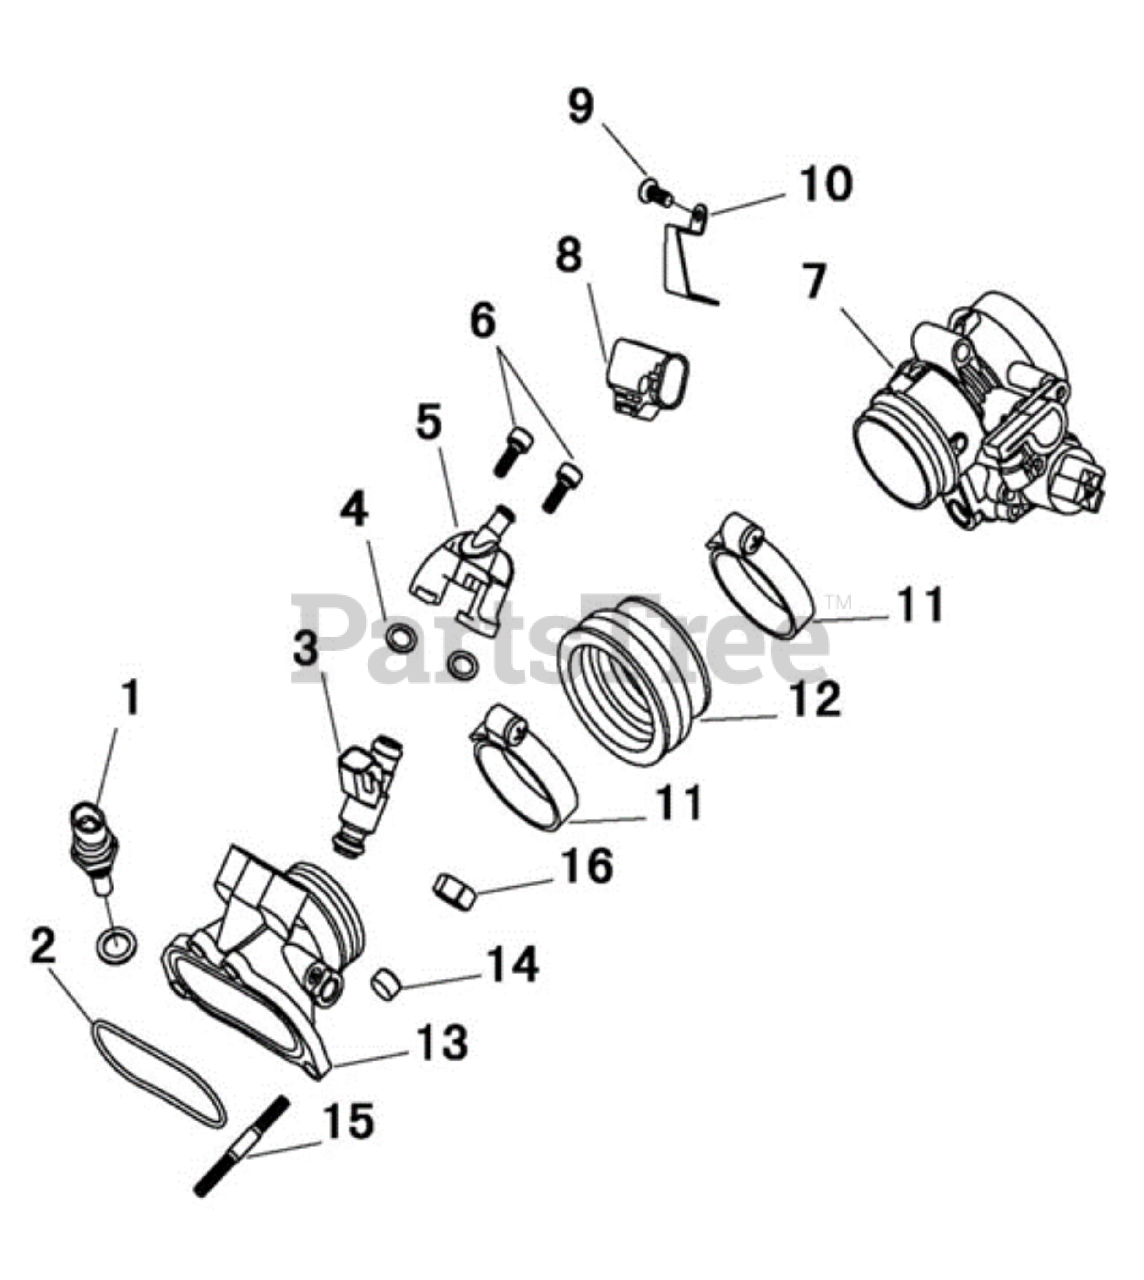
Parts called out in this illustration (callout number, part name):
1	Water Temperature Sensor
2	Seal,intake-tube
3	Fuel Injector?25377439?
4	Washer 6X12X2
5	Permanent Seat,Fuel Injector
6	Hexagon socket head cap screws M6X20
7	Throttle Body Assy?D46-3?
8	Temperature/Pressure Sensor
9	Cross recessed pan head screw, single coil spring lock washer assemblies M4X8
10	Press Plate,TMAP
11	Hose Clamp Assy 50?70
12	Intake-tube join
13	Intake-tube Assy
14	Bushing 7X9X8
15	Stud M6X32
16	Nut M6
